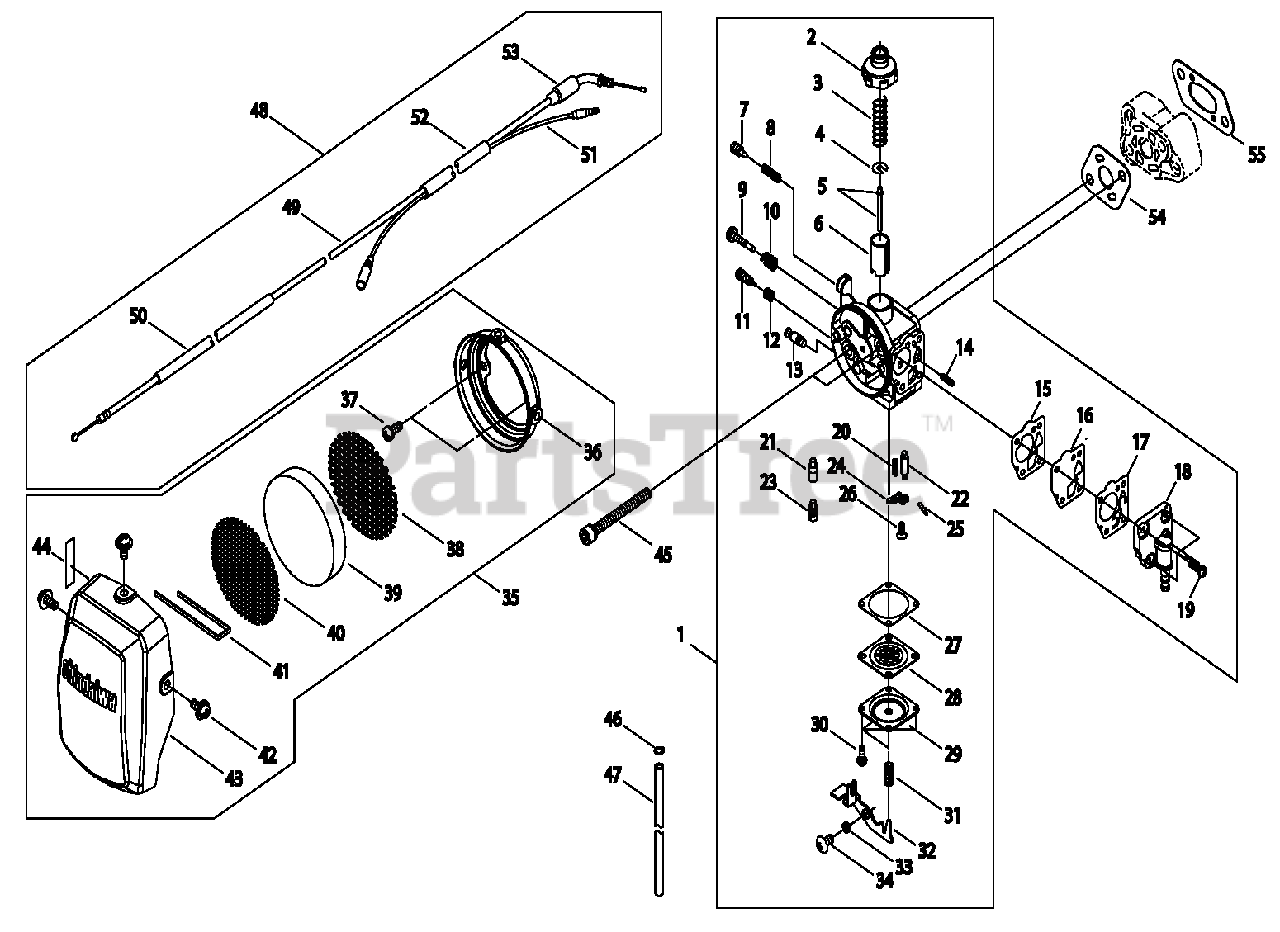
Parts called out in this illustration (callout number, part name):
1	CARBURETOR
2	CAP, THROTTLE
3	SPRING
4	WASHER, SPRING SUPPORT
5	NEEDLE, JET
6	VALVE, THROTTLE
7	SCREW, SLOW AIR
8	SPRING
9	SCREW, IDLE ADJUST
10	SPRING
11	SCREW, MAIN ADJUST
12	SPRING
13	VALVE, OVERFLOW
14	SPRING, COIL
15	GASKET, DIAPHRAGM
16	DIAPHRAGM, METERING
17	VALVE, PUMP
18	BODY, PUMP
19	SCREW
20	SPRING
21	JET, MAIN
22	VALVE, INLET NEEDLE
23	HOLDER, MAIN JET
24	LEVER, METERING
25	PIN, METERING LEVER
26	SCREW M3×8
27	GASKET, METERING DIAPHRAGM
28	DIAPHRAGM, METERING
29	COVER, DIAPHRAGM
30	SCREW M3×8
31	SPRING
32	LEVER, TICKLER
33	COLLAR
34	SCREW
35	FILTER ASSY, AIR
36	CASE, AIR FILTER
37	SCREW
38	SCREEN, REAR
39	FILTER, AIR
40	SCREEN - FRONT
41	CLIP, FILTER RETAINING
42	SCREW 4
43	COVER, AIR FILTER
44	LABEL, CHOKE
45	BOLT M5×50
46	CLIP Ø6
47	PIPE, FUEL
48	CABLE ASSY, CONTROL
49	CABLE, THROTTLE
50	TUBE, THROTTLE CABLE
51	LEAD
52	TUBE, PROTECTIVE
53	CAP, CARBURETOR
54	GASKET, CARBURETOR
55	INSULATOR, INTAKE
